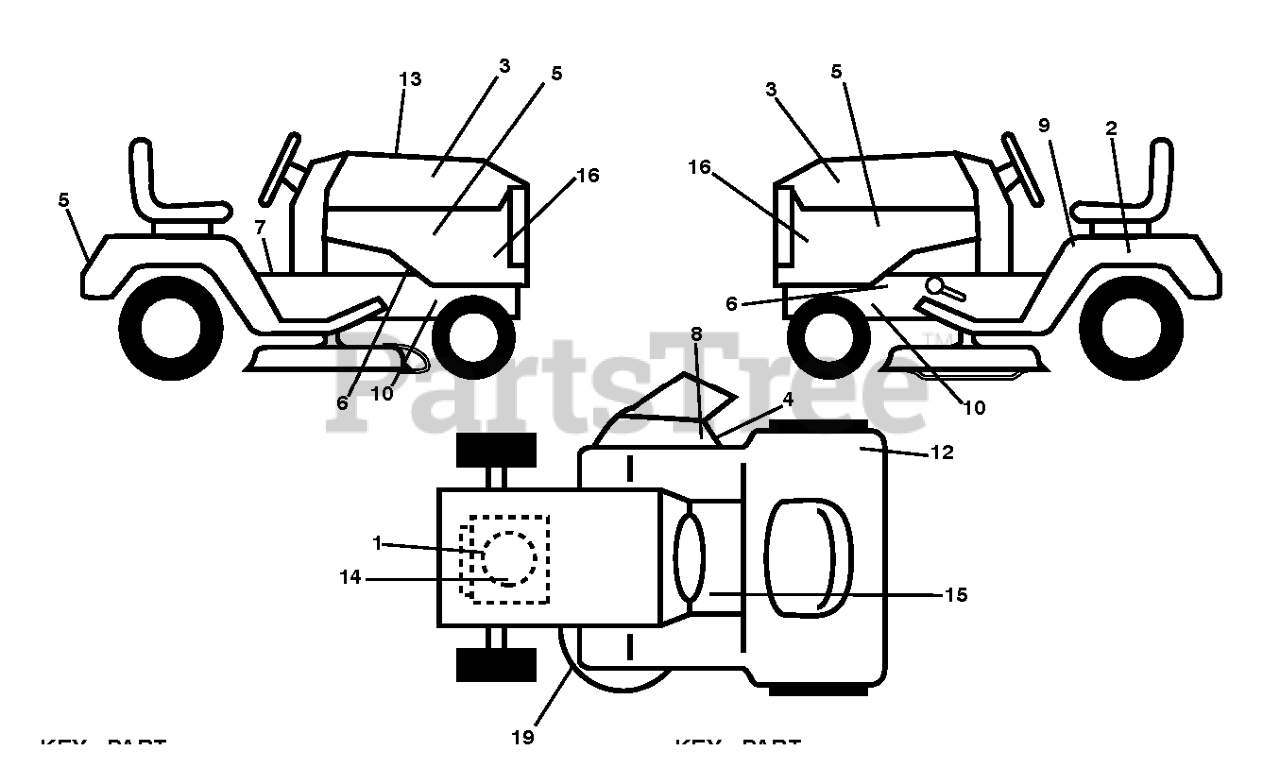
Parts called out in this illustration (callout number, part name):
1	DECAL.ENGINE.WARNING
2	DECAL BTRY SYMBOLS
4	DECAL.DFLCTR.WARNNG.CTFNGR.SYM
5	DECAL HOOD
6	DECAL.WARNING.SERVCE/FIRE
7	DECAL.PARKING.BRAKE.SADDLE.LT
8	DECAL, DECK DEFLECTOR, WARNING
9	DECAL.READ.OWN.MAN.SYMBOL.LT
10	DECAL.CHASSIS.HOT.MUFFLER
12	DECAL.CERTIFICATION.6MIL.100D
14	DECAL
15	DECAL.FNDR.SDLE.BRAKE.CLUTCH.6
19	DECAL.DECK.SCH.36,38,94.NONCR
